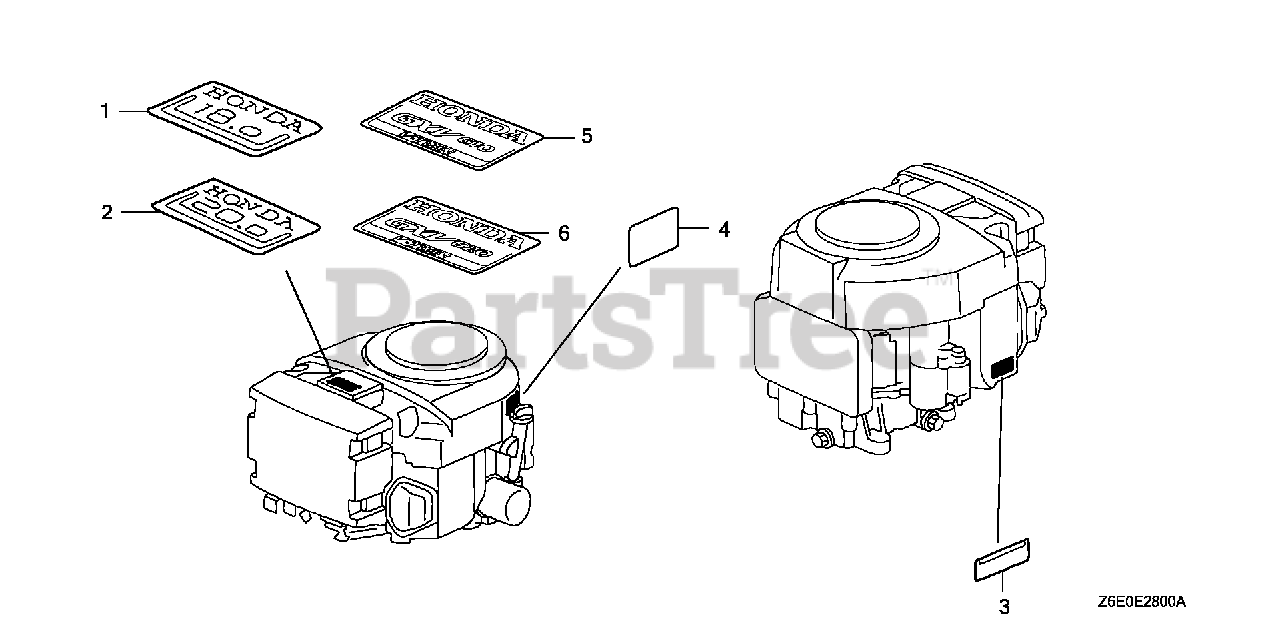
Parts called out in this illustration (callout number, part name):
1	EMBLEM (GX610)
3	LABEL, SPECIFICATION (GXV610)
4	MARK, OPERATOR CAUTION (ENGLISH)(MADE IN JAPAN)
4	MARK, OPERATOR CAUTION (PICTOGRAPH)(MADE IN JAPAN)
4	MARK, OPERATOR CAUTION (PICTOGRAPH)
5	MARK, EMBLEM (GXV610)
